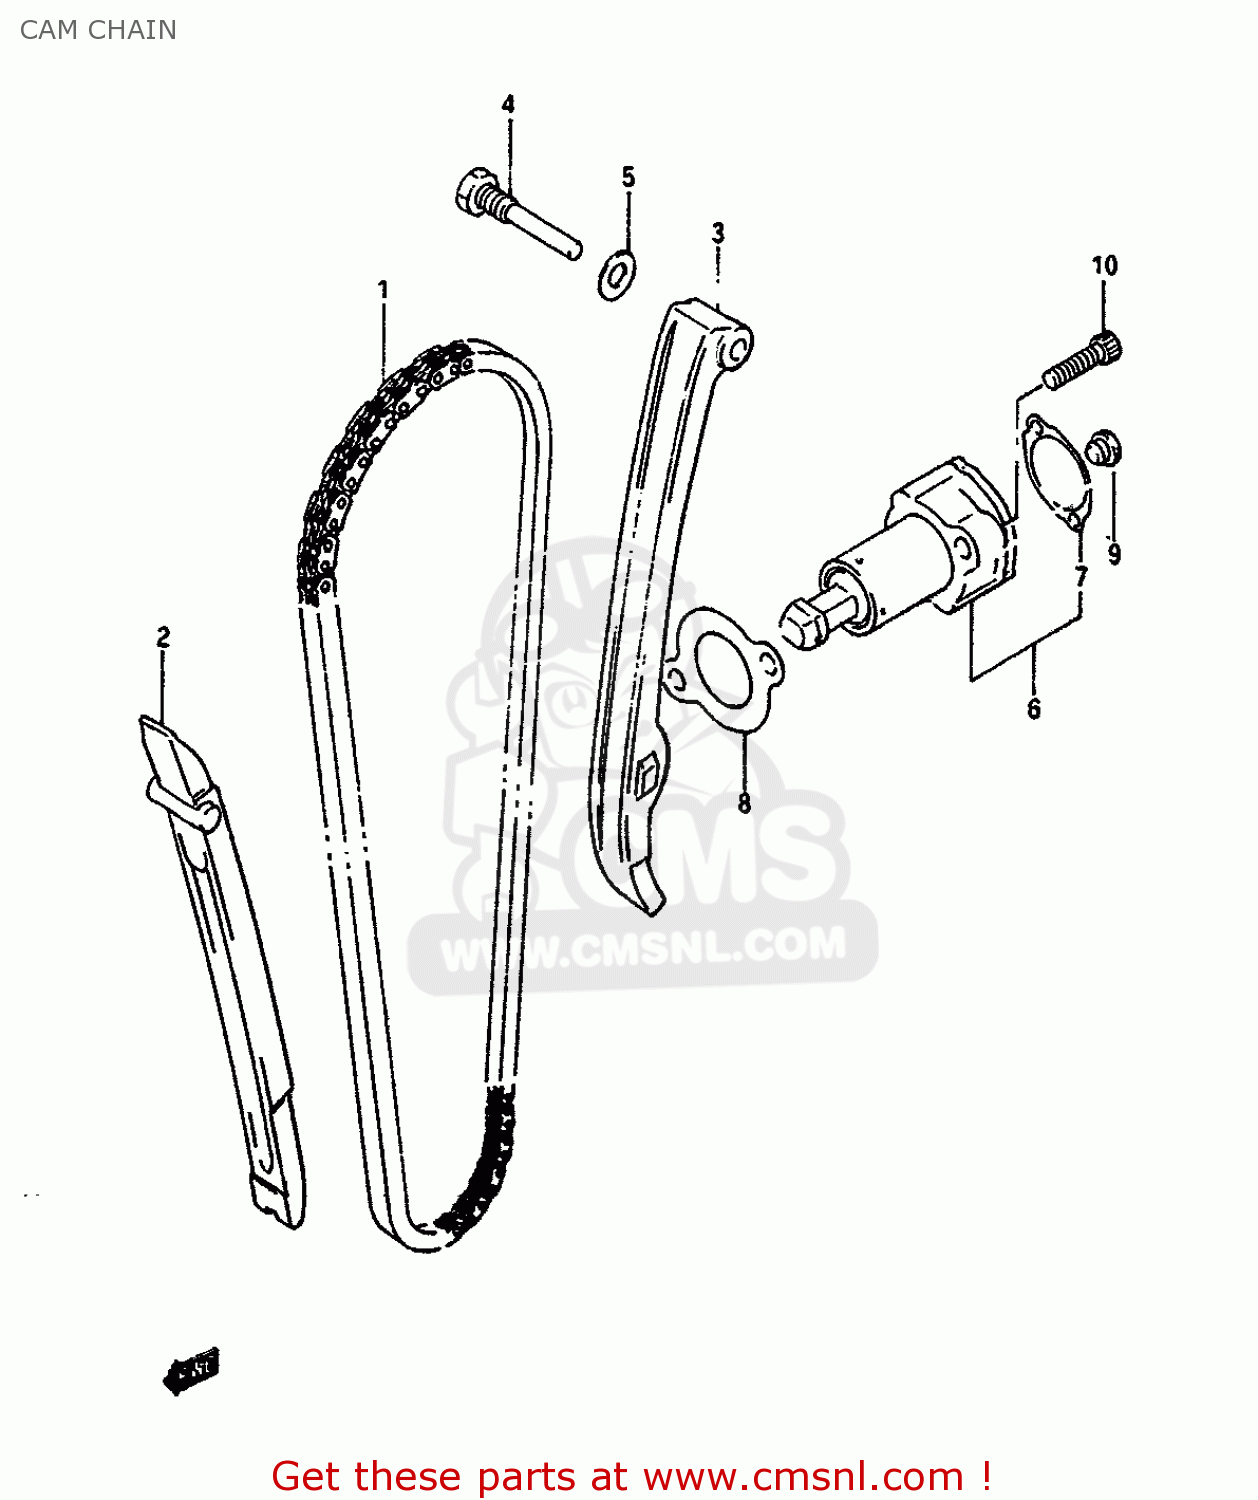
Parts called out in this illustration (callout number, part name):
1	CHAIN,CAMSHAFT DRIVE
2	GUIDE,CAM CHAIN
3	TENSIONER,CAM CHAIN
4	BOLT,CAM CHAIN TENSIONER
5	GASKET 8.2X14X1 (NAS)
6	ADJUSTER ASSEMBLY,TENSIONER
7	GASKET,ADJUSTER CAP (MCA)
8	GASKET,TENSIONER ADJUSTER
9	PLUG,ADJUSTER
10	BOLT
